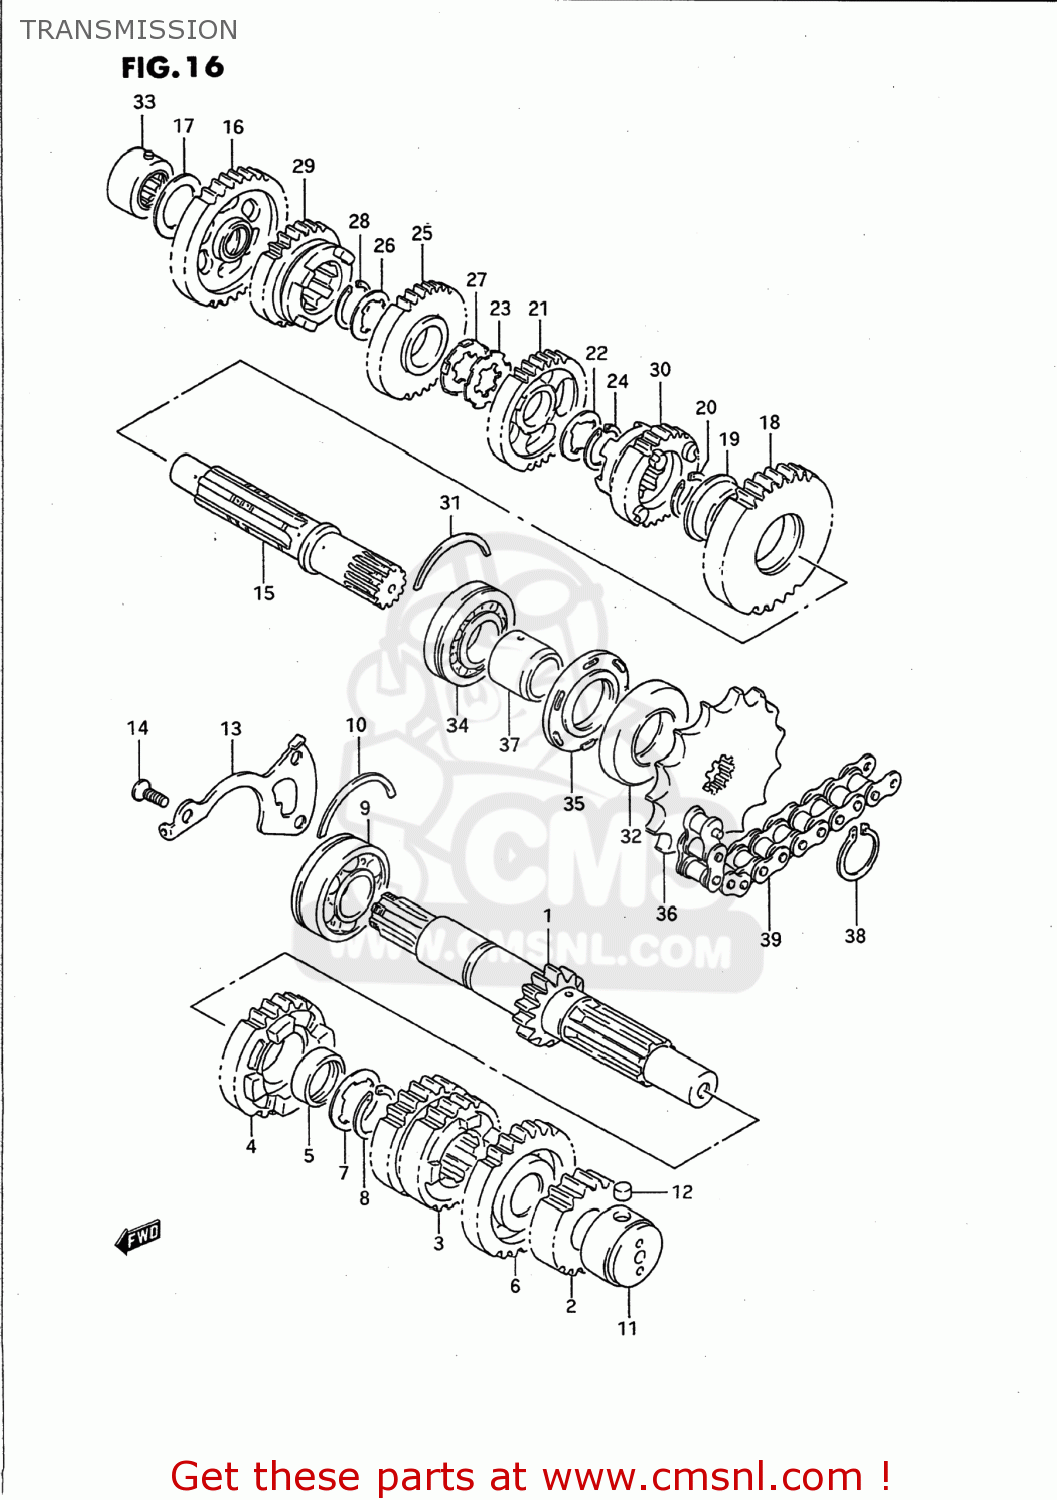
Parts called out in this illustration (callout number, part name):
1	SHAFT,COUNTER (NT:13)
2	GEAR,2ND DRIVE(NT:18)
3	GEAR,THIRD DRIVE (NT:21/2
4	GEAR,FIFTH DRIVE (NT:26)
5	BUSHING 25X29X10
6	GEAR,SIXTH DRIVE (NT:27)
7	WASHER
8	CIRCLIP
9	BEARING(25X62X17)
10	C-RING
11	ROLLER BEARING (20X34X2
12	PIN
13	PLATE,COUNTERSHAFT BEARING
14	SCREW ,6X16
15	SHAFT,DRIVE
16	GEAR,FIRST DRIVEN
17	WASHER
18	GEAR,SECOND DRIVEN
19	BUSHING
20	CIRCLIP
21	GEAR,THIRD DRIVEN
22	WASHER,LOCK
23	WASHER,LOCK
24	CIRCLIP
25	GEAR,FOURTH DRIVEN
26	WASHER,LOCK
27	WASHER
28	CIRCLIP
29	GEAR,5TH DRIVEN(NT:25)
30	GEAR,SIXTH DRIVEN
31	C-RING
32	SEAL,OIL(32X62X7)
33	ROLLER BEARING (20X34X1
34	BEARING(25X62X17)
35	SEAL,OIL(32X62X5.5)
36	SPROCKET,ENGINE
37	SPACER,ENGINE SPROCKET
38	CIRCLIP
39	CHAIN ASSEMBLY,DRIVE
